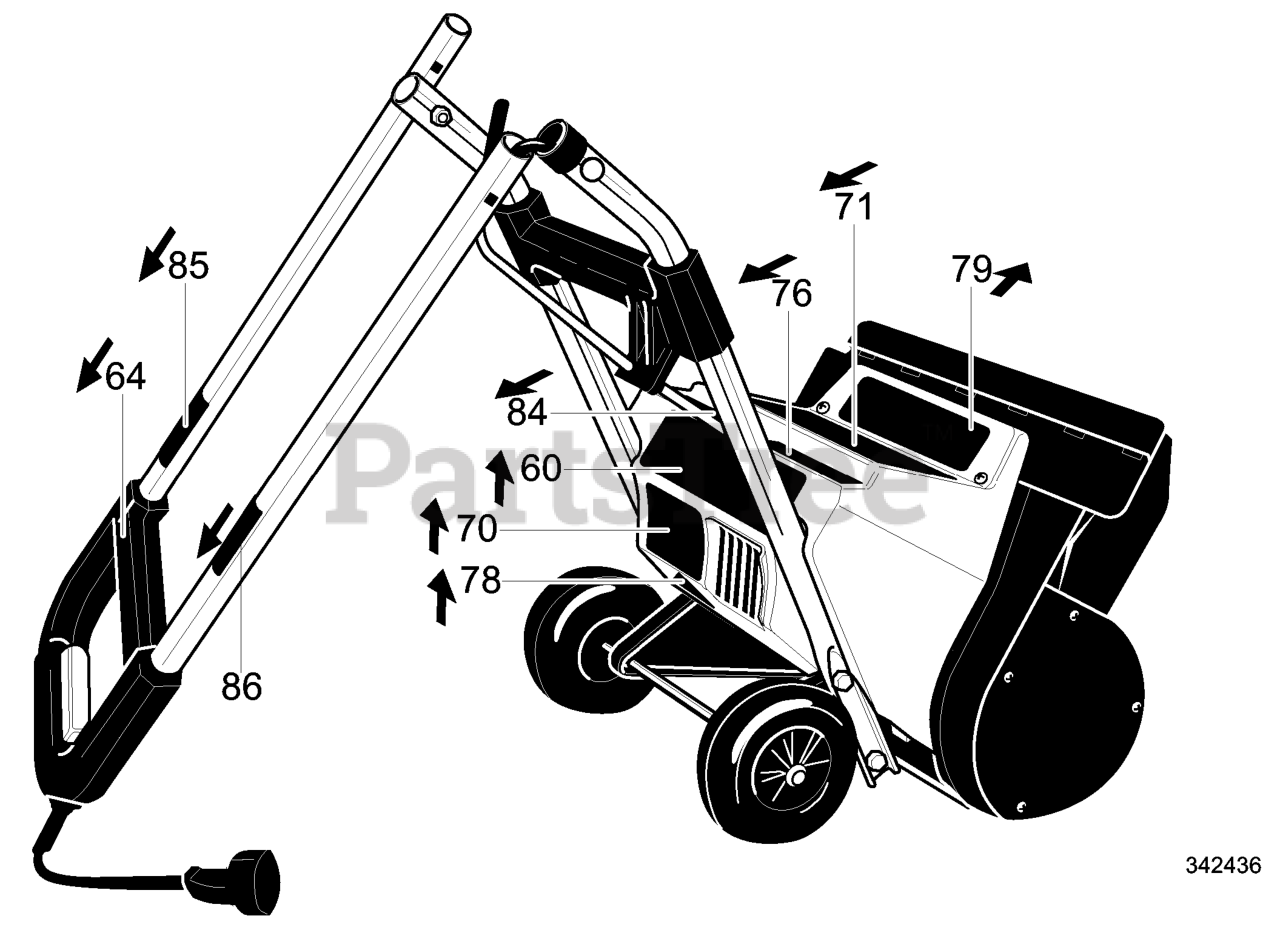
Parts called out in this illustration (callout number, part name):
60	Decal, Safe Operation
64	Decal, Start & Stop
70	NOT SERVICEABLE
71	Decal, MURRAY TURBO
76	Decal, Discharge Control
79	Decal, Danger Foot
84	Decal, Warning Cut-Out
85	Decal, Motor Protection, English
86	Decal, Motor Protection, French
